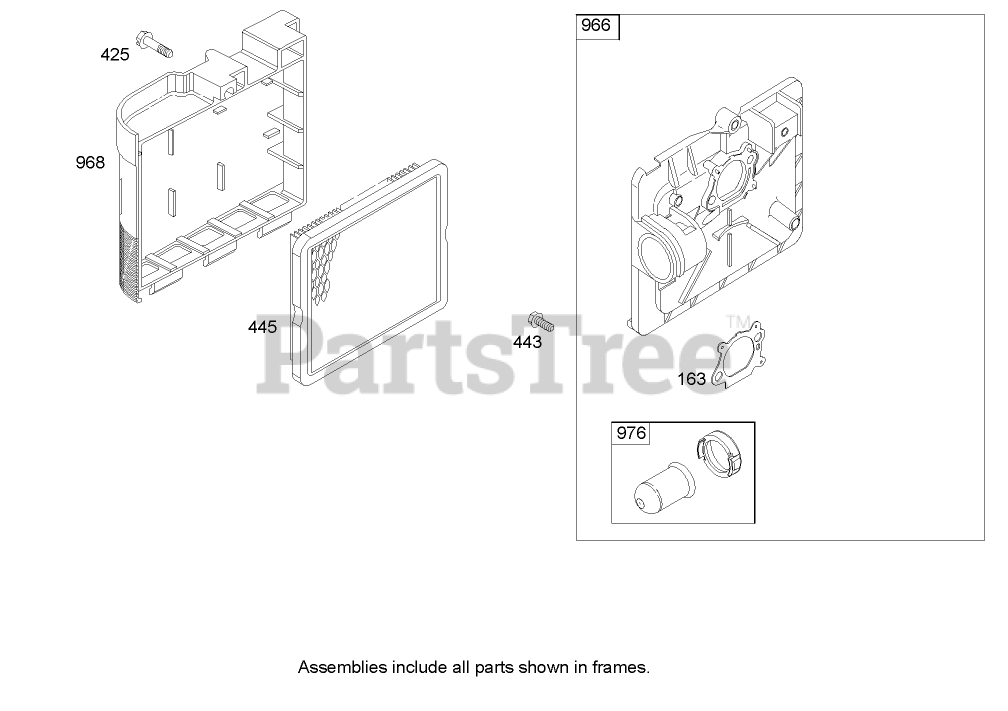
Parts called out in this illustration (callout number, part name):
163	Gasket-Cleaner, Air
425	Screw
443	Screw
445	Filter-Air Cleaner, Cartridge
966	Base-Primer, Air Cleaner
968	Cover-Cleaner, Air
976	Primer-Carburetor
